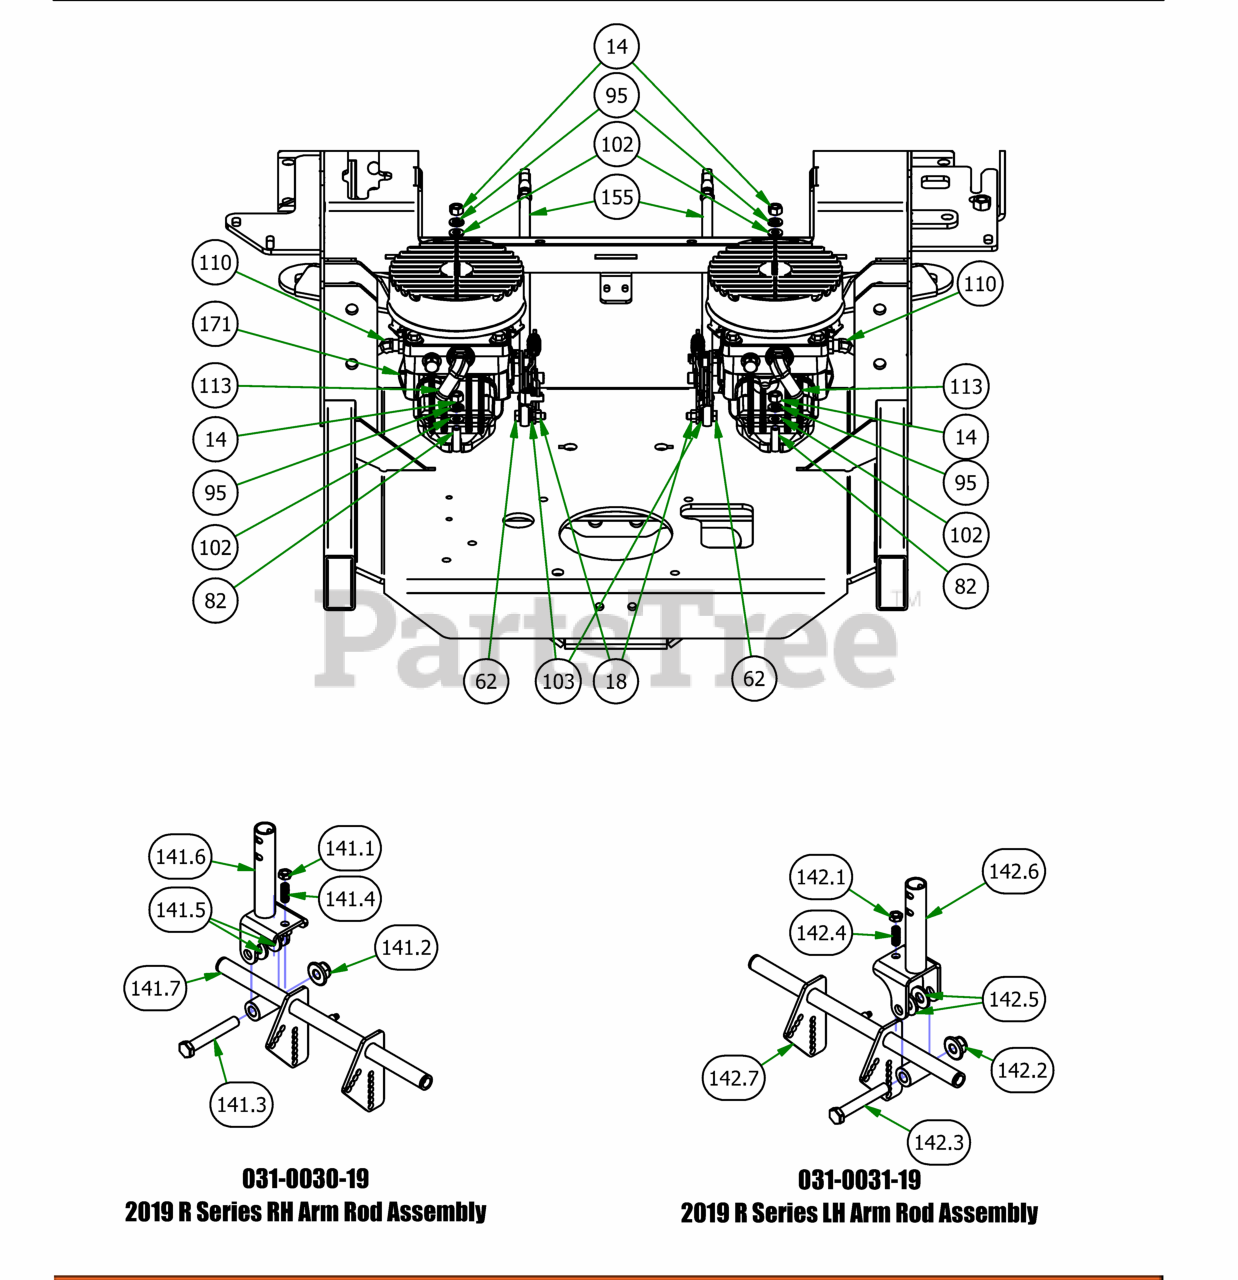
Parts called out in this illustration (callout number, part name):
14	3/8" Hex Nut
62	5/16 x 1 1/4 Hex Bolt
82	3/8 x 1 1/2 Bolt
95	3/8" Lock Washer
102	5/16" Flat Washer
103	5/16" Lock Washer
110	ZT Fitting, 3/8 x 3/8 45 Degree, 4603-6-6
113	90 Degree Fitting, 1/2 x 3/4, 4601-8-8
141.1	3/8-16 Half Jam Nut
141.2	1/2-13 NYLON INSERT FLANGE LOCKNUT ZINC
141.3	1/2-13 x 3.25 GR 5 Hex Bolt Zinc
141.4	3/8-16 x 1 Set Socket Set Screw Cup Point
141.5	.505 Nylon Spacer
141.6	Drive Arm Pivot
141.7	2019 Drive Arm Actuator right
142.1	3/8-16 Half Jam Nut
142.2	1/2-13 NYLON INSERT FLANGE LOCKNUT ZINC
142.3	1/2-13 x 3.25 GR 5 Hex Bolt Zinc
142.4	3/8-16 x 1 Set Socket Set Screw Cup Point
142.5	.505 Nylon Spacer
142.6	Drive Arm Pivot
142.7	2019 Drive Arm Actuator left
155	2019 Outlaw Gen2 XP Push Rod Assembly
171	2019 Rogue/Renegade Left Pump 16cc
